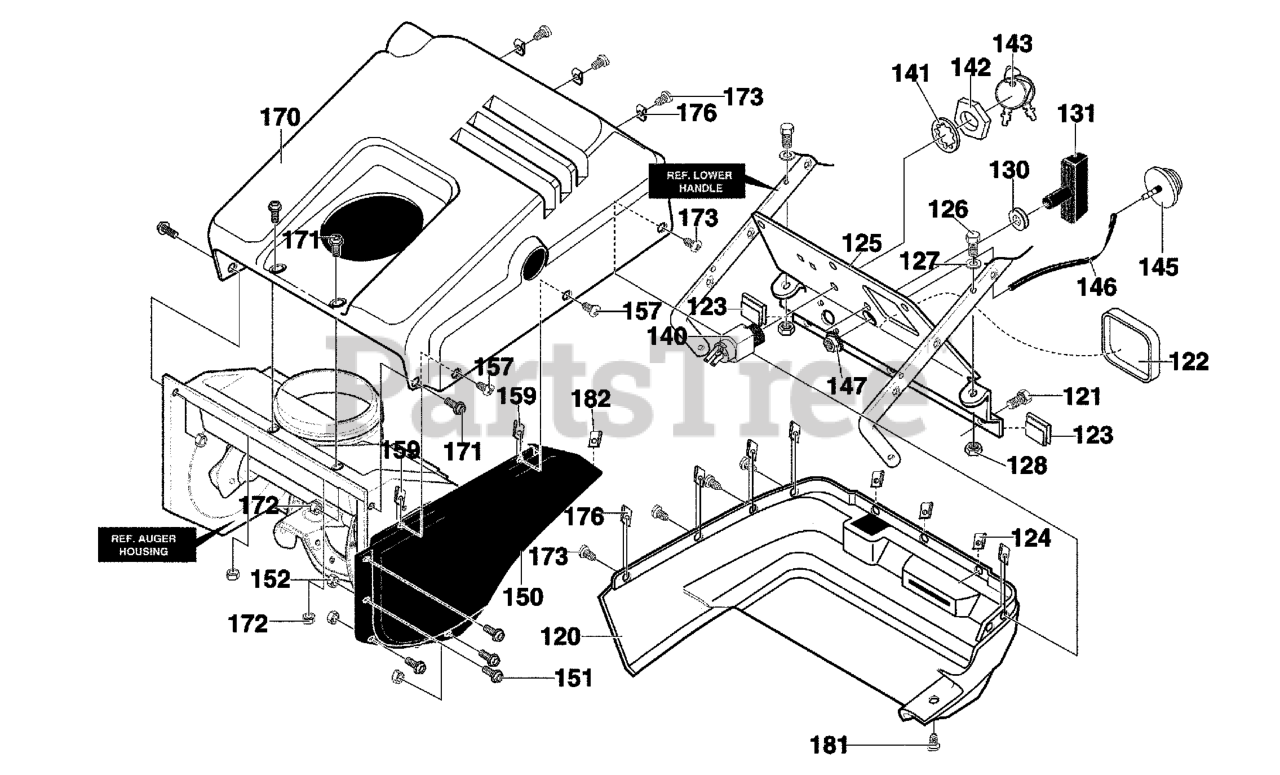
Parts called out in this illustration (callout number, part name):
120	COVER, BOTTOM
121	SCREW, 1/4-14X.75
122	PANEL, SPARK ACCESS
123	CLIP, "S" TINNERMAN
124	NUT, 1/4-10 SPEED J TYPE
125	CONTROL PANEL
126	SCREW, 1/4-20X1.25
127	FLATWASHER, .281X.63X.065
128	NUT, 1/4-20 REGHEXCTRLK
130	GOMMET & WASHER
131	KNOB T
140	SWITCH, IGNIT.
141	WASHER, REGINTLK .640X1.1X.05
142	NUT. 5/8-32
143	KEYS & RING
145	PRIMERBULB
146	HOSE PRIM 9.50LG
147	NUT, 1/4-20 REGHEXKEPS
150	COVER, BELT
151	SCREW, 10-24X.50
152	NUT, #10-24 REGHEXCTRLK
157	SCREW, 1/4-14X.75
159	NUT, 1/4-10 SPEED J TYPE
170	COVER, TOP
171	SCREW,#10-24X.50
172	NUT #10-24 REGHEXCTRLK
173	SCREW, 1/4-14X.75
176	NUT, 1/4-10 SPEED J TYPE
181	SCREW, 1/4-14X.75
182	NUT 1/4-10 SPEED J TYPE
